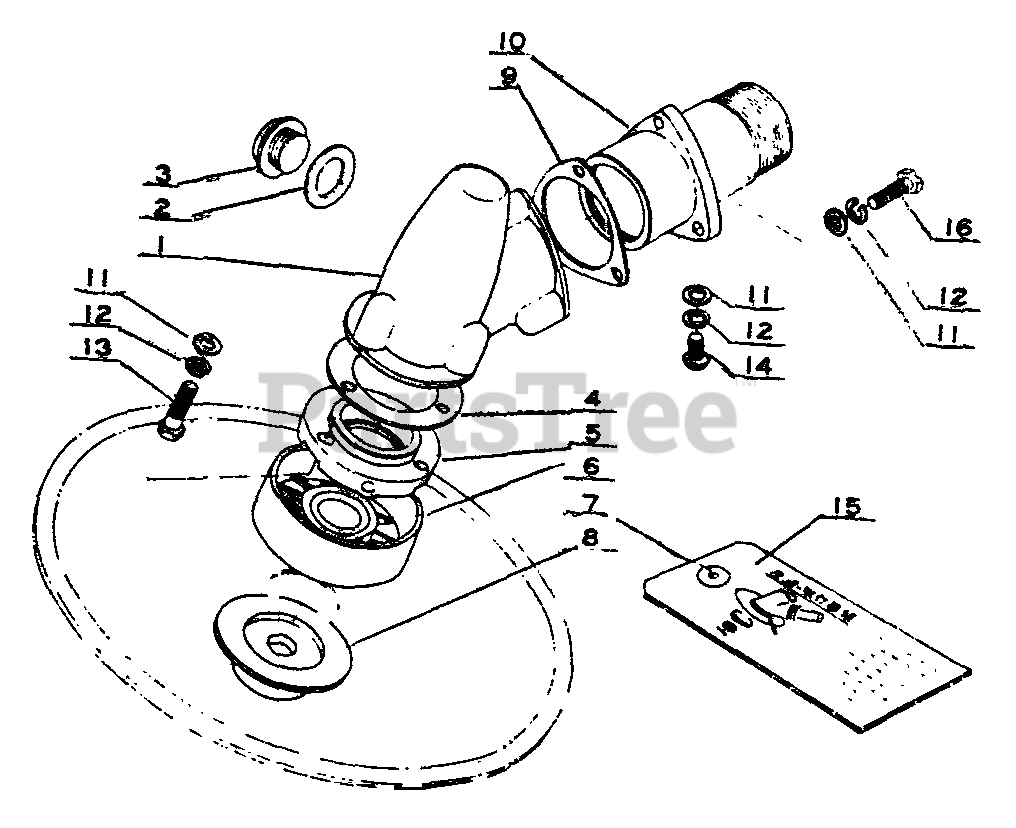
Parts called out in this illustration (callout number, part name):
1	CASE, GEAR
4	GASKET, GEAR CASE
5	HOLDER, BEARING - B
6	Fitting plate (A)
8	Fitting plate (B)
9	GASKET, GEAR CASE
10	HOLDER, BEARING - A
11	WASHER - 5
12	LOCKWASHER - 5
13	BOLT - 5X16
14	SCREW - 5X8
16	SCREW - 5X18
